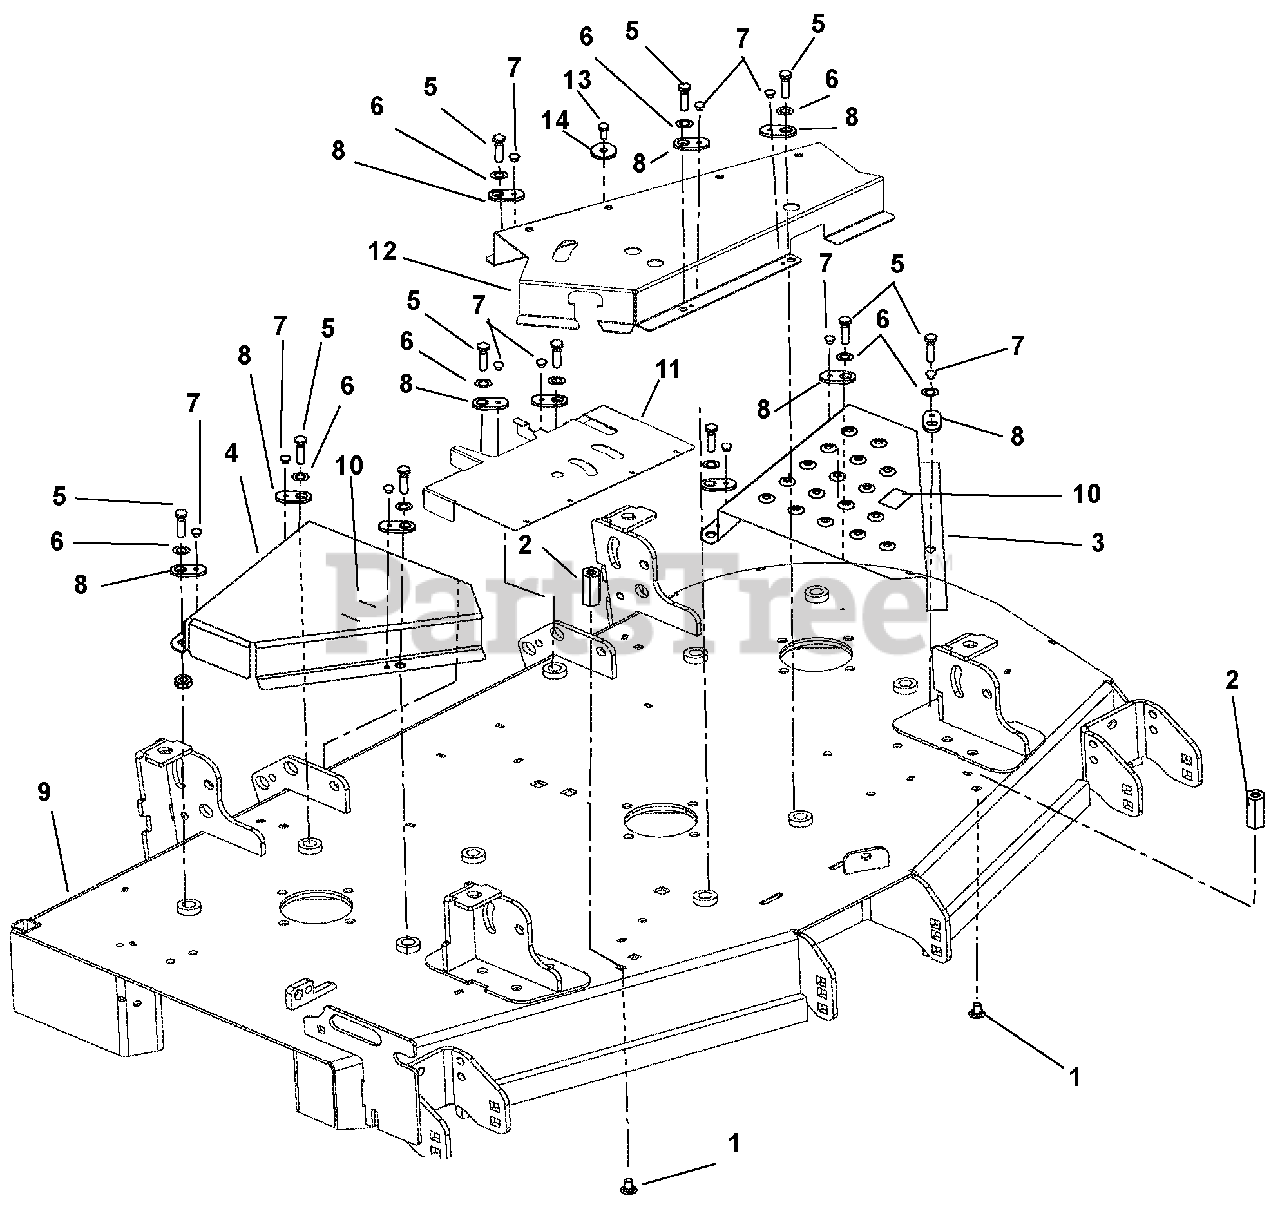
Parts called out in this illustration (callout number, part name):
1	Bolt, Round Head Square Neck .31-18 x .75
2	Nut, Coupling .31-18 x 3.00
3	Cover, Belt, CE Left Hand
4	Cover, CE Belt Right Hand
5	Bolt, Hex .38-16 x 1.25
6	Washer, Locking, EXT .391 x .682 x .036
7	Rivet, Pop .187
8	Keeper, Bolt
9	Weldment, 48" PT100 Side Dis Deck, CE
10	Decal, Pinch Point
11	Shield, Belt, Rear
12	Shield, Belt, Front
13	Bolt, Hex .25-20 x .75 Grade 5 YZ
14	Washer, Flat Steel .281 x .62 x .065 YZ
